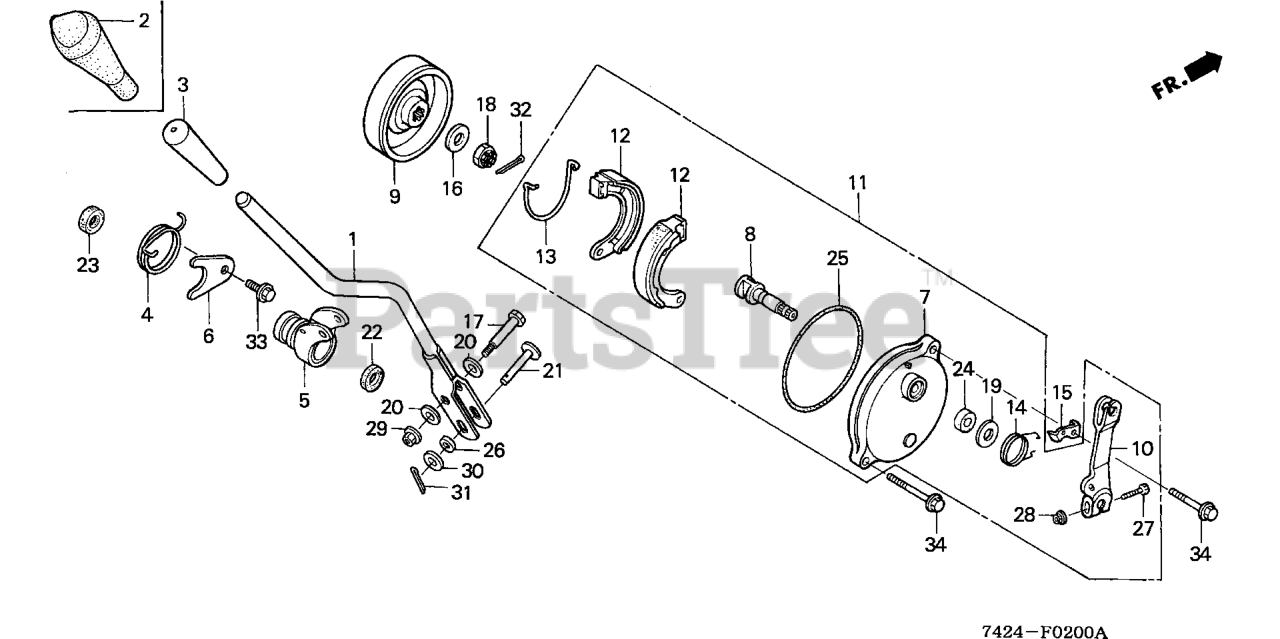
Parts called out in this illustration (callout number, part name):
1	LEVER, CHANGE
3	GRIP, CHANGE LEVER (ORANGE)
4	SPRING, SELECT LEVER RETURN
5	HOLDER, SELECT LEVER
6	STOPPER, PLATE
7	PANEL, BRAKE
8	CAM, BRAKE
9	DRUM, BRAKE
10	ARM, BRAKE
11	PANEL ASSY., BRAKE
12	SHOE, BRAKE (ASK)
13	SPRING, BRAKE SHOE
14	SPRING, BRAKE ARM
15	PLATE, BRAKE ARM SPRING
16	WASHER (10MM)
17	BOLT, HOLDER
18	NUT, CASTLE (10MM)
19	WASHER (10.5MM)
20	WASHER (8.3MM)
21	PIN, CHANGE LEVER
22	OIL SEAL (15X24X5)
23	DUST SEAL (15X21X3)
24	SEAL, BRAKE CAM
25	O-RING (100X2)
26	COLLAR, CHANGE JOINT
27	BOLT, HEX. (5X28)
28	NUT, FLANGE (5MM)
29	NUT, SELF-LOCK (6MM)
30	WASHER, PLAIN (6MM)
31	PIN, COTTER (1.6X25)
32	PIN, COTTER (2.0X22)
32	PIN, COTTER (2.0X35)
33	BOLT, FLANGE (8X14)
34	BOLT, FLANGE (6X28)
